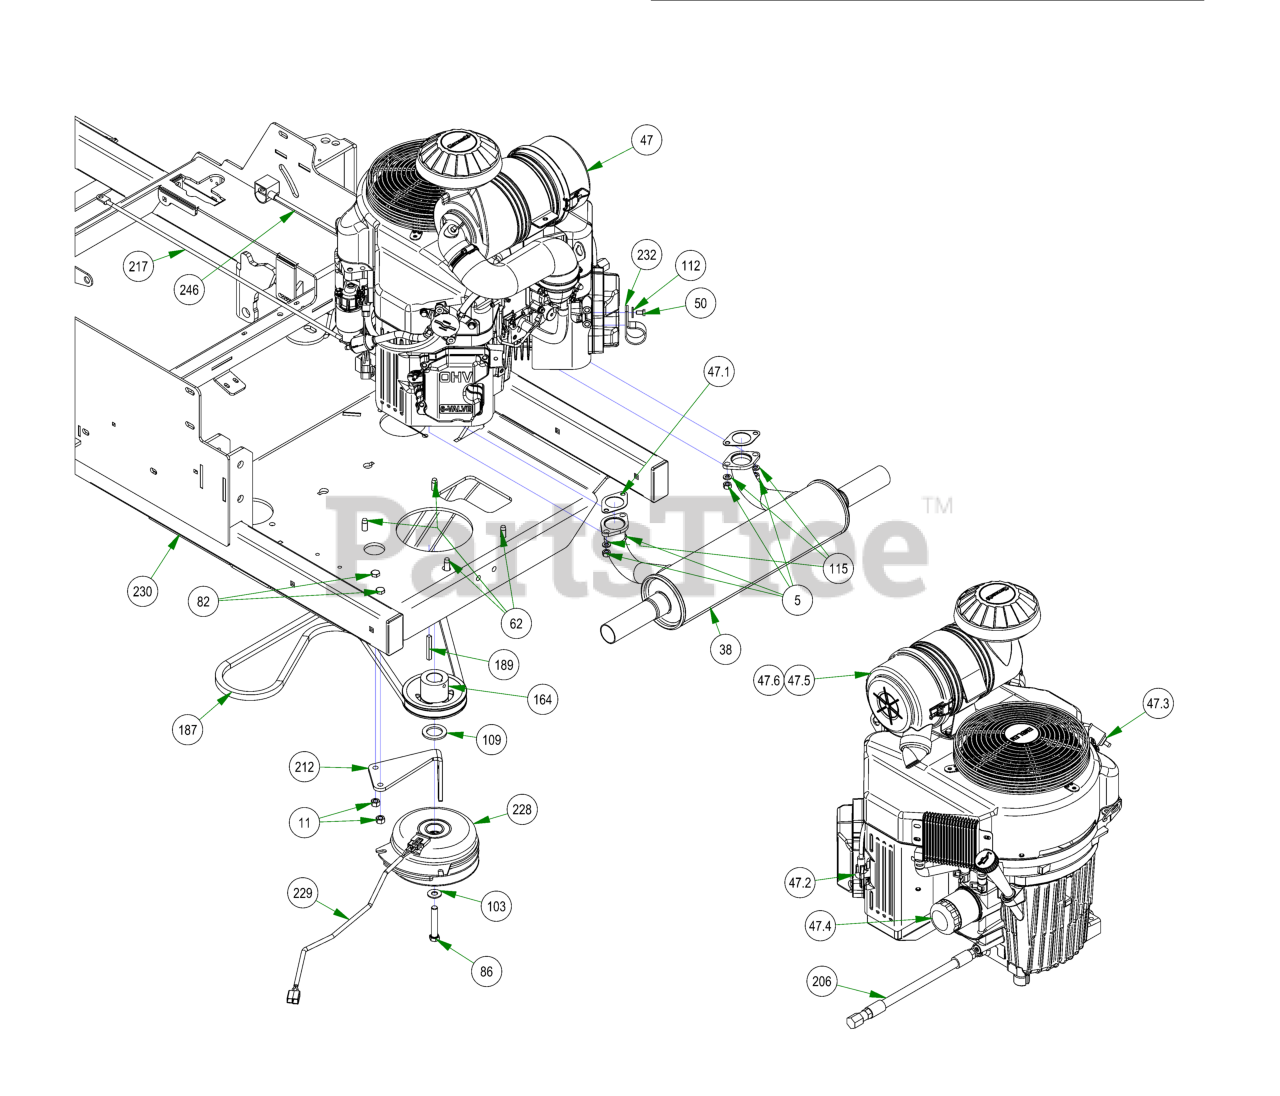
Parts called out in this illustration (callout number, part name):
5	M8-1.25 DIN 934 HEX NUT (CL.8) ZINC
11	3/8-16 HEX NUT ZINC
31	1 1/2 x 3 Frame Plug
38	2019 Rebel/Rogue Kawasaki 1000 Muffler
47	Kawasaki FX1000 Engine
47.1	Exhaust Gasket
47.2	Spark Plug - Kawasaki
47.3	Universal Inline Fuel Filter
47.4	Oil Filter
47.5	Canister Air Filter- Outer
47.6	Canister Air Filter- Inner
50	M6-1.0 X 12MM DIN 933 HEX TAP BOLT (CL 8.8) ZINC
62	3/8-16 X 1-1/8HEX WASHER UNSLOT SERRATED
82	3/8-16 X 1-1/4 HEX CAP SCREW (GR.5) ZINC
86	7/16-20 X 2-1/2 HEX Bolt GR 8 W/ Patch
103	3/8 FLAT WASHER USS (1" OD) ZINC
109	1.140 ID X 1.750 OD X .132 THICK FLAT WASHER PLAIN
112	1/4 USS FLAT WASHER (3/4 OD) ZINC
115	5/16 SPLIT LOCKWASHER ZINC
164	4 3/4 Motor Pulley
187	2019 Rogue Pump Belt 68"
189	1/4 X 2 SQ MACHINERY KEY 1018 STL PLAIN
206	Kawasaki Oil Drain
212	PTO Engager Holder
217	24" Red Battery Cable
228	Clutch Assembly
229	Clutch Pigtail
230	2021 Rogue Suspension Frame Painted
232	Diesel Hydraulic Hose Clamp
246	Starter Cable
248	2019 Harness Adaptor-Gen2 FX-ALL
